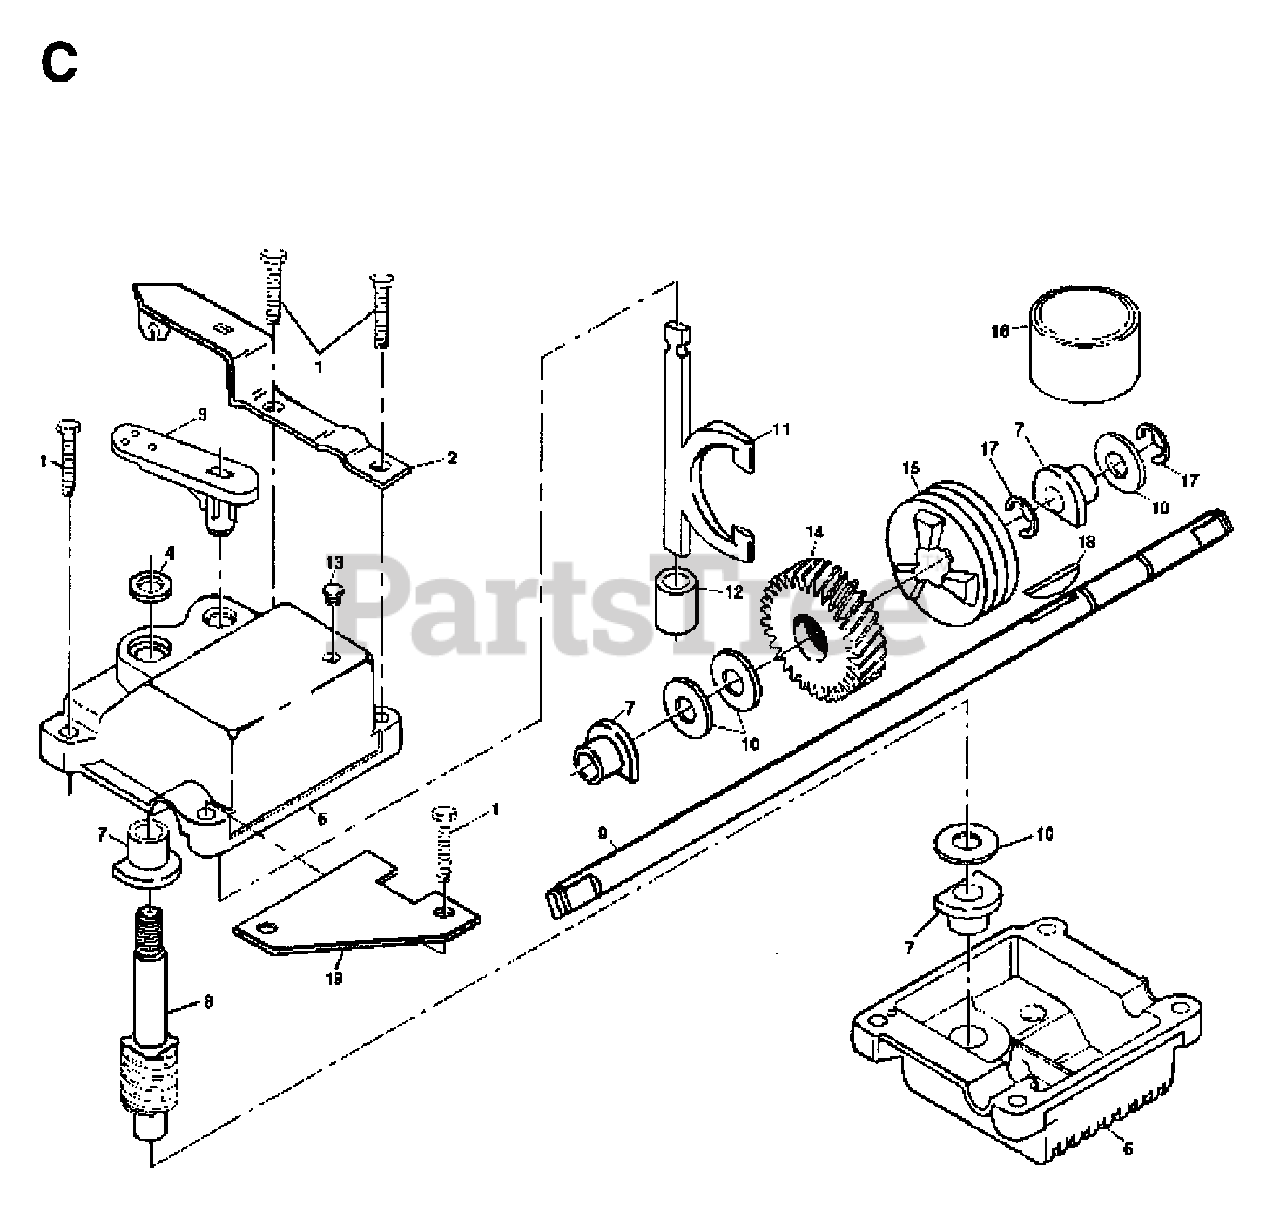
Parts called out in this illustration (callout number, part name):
1	SCREW
2	BRACKET
6	GEAR CASE
8	WORM SHAFT
9	DRIVE SHAFT, 20-5/8"
10	THRUST WASHER
11	YOKE CLUTCH
14	GEAR.HELICAL
15	CLUTCH JAW
16	GREASE
18	HI PRO KEY
19	BRACKET SPRING
